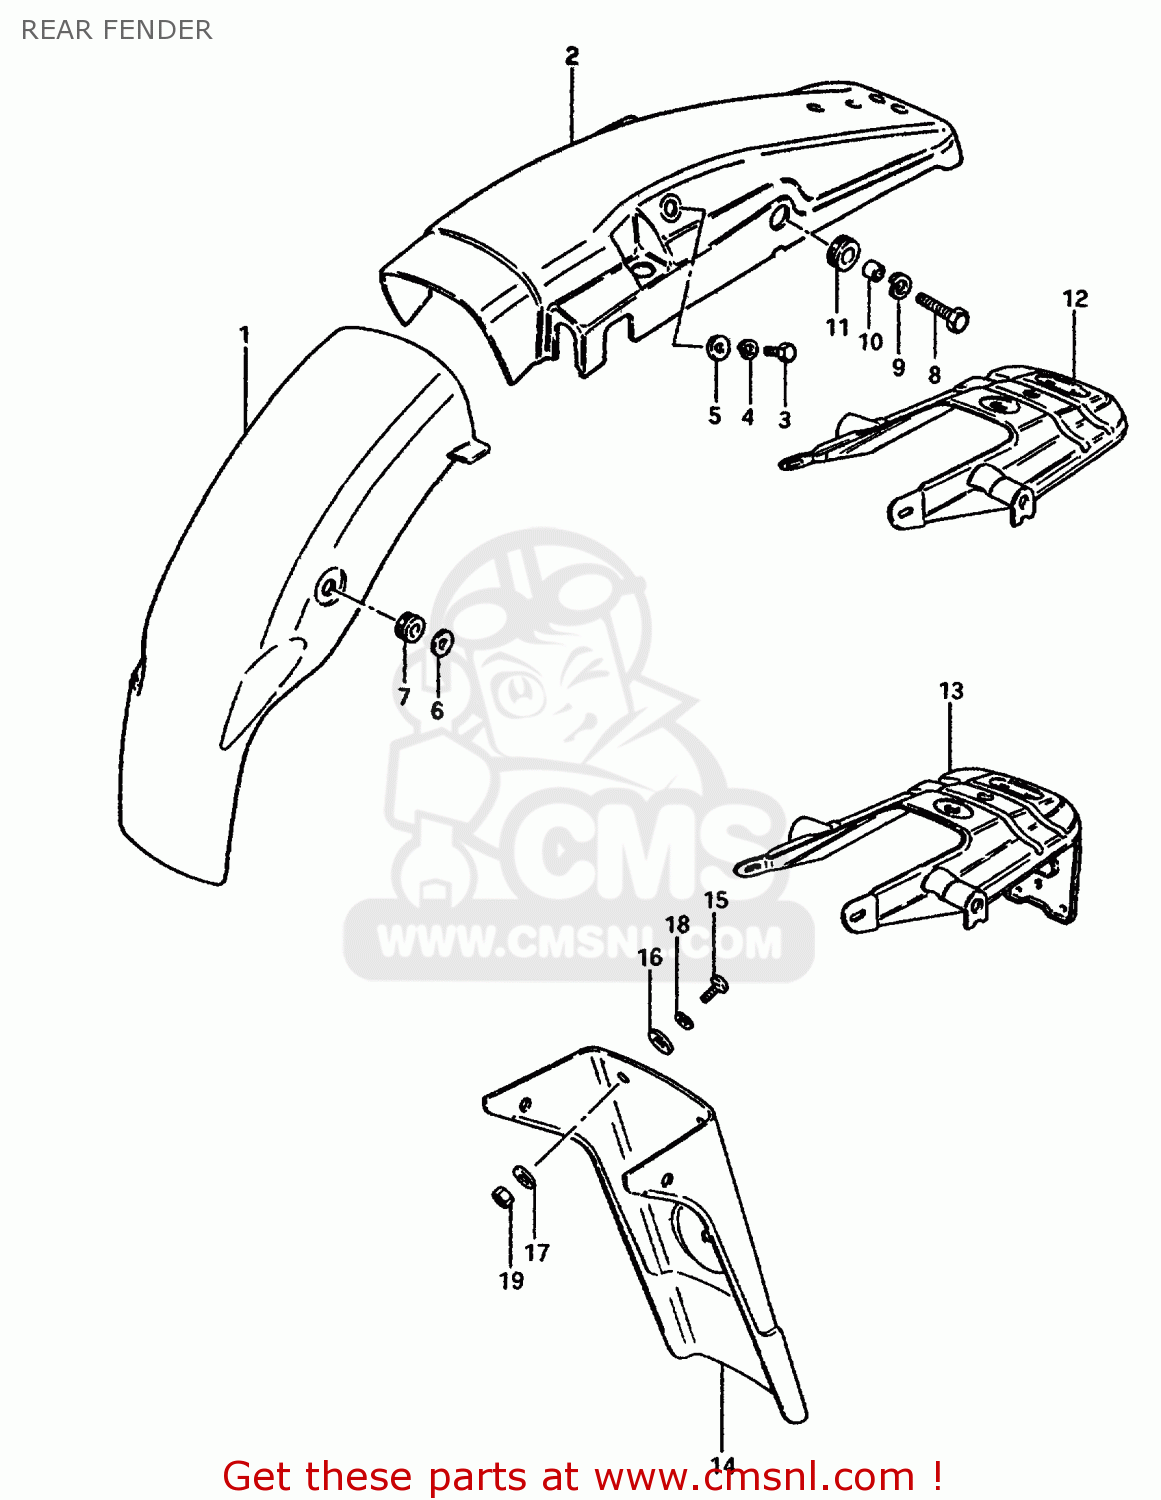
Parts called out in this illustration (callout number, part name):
1	BODY, REAR FENDER FRONT
2	BODY, REAR FENDER REAR
3	BOLT, UPPER
4	LOCK WASHER
5	WASHER
6	WASHER
7	CUSHION
8	BOLT 8X55
9	LOCK WASHER
10	SPACER (8.2X12X7.5)
11	CUSHION
12	REINFORCEMENT
13	REINFORCEMENT
14	MUD GUARD, REAR FENDER
15	SCREW
16	WASHER (6.5X18X1.6)
17	WASHER
18	LOCK WASHER
19	NUT
